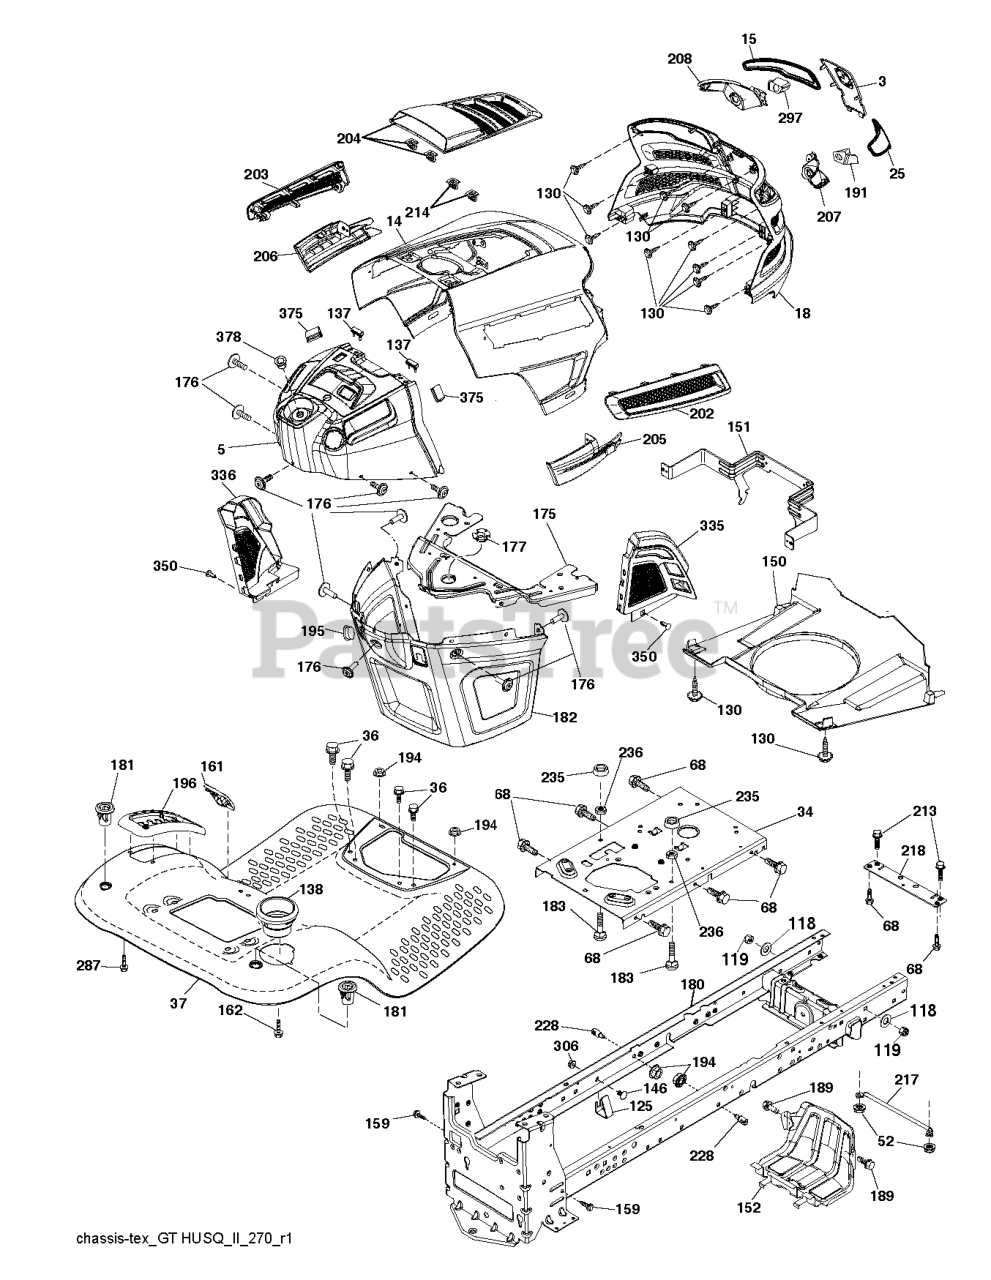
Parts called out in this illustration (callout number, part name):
3	APPLIQUE.SUBASM.GT.HUSQ.II
5	DASH.UPPER.ASM.GT2.SRV.MND.MAN
5	DASHBOARD.UPPER.ASM.GT2.X498
14	HOOD.ASM.HUSQVARNA.GT.TEX.ORAN
15	LENS.HEADLIGHT.LH.GTII.2011
18	Grilles
18	GRILLE SUBASM.GT.II.LOW.HDLGHT
25	LENS.HEADLIGHT.RH.GTII.2011
34	PLATE.ENGINE.WELDED.CHASSIS
36	SCREW 5/16"
37	FENDER.TLT.PDL.CNTRL.W/CPH.ORG
37	FENDER.TLT.FS.W/CPH/FW/RSF.668
118	WASHER
119	Nuts
125	CLIP.FUEL.LINE
137	BUMPER DASH
138	HOLDER.CUP.LT.GREY
146	BOLT.RDHD.SHT.SQNK.3/8-16X5/8
150	AIR.DUCT.GTV2(2.54"RING HEIGHT
150	AIR DUCT.GTV2(1.66"RING HEIGHT
151	BRACKET.PIVOT.HOOD.GT.HUSQ.II
152	SHIELD.BROWNING.PNT.GT.V2
159	SCREW, 3/8-16X3/4
161	WINDOW.FUEL.LT.HUSQ.TEX.498
175	PLATE.PNT.CROSSMEMBER.HUSQ/PRE
176	SCREW.#10-24X5/8.RN.QU
177	BUSHING STEERING
180	CHASSIS
181	BUSHING.MNT.FEND.CRGO.TEX.49
182	DASH.LOWER.COMMON.12V.ADAPTOR
182	DASH LOWER.HUSQ.PRED NO CRUISE
189	SCREW
191	INSERT.REFLECTIVE.RH.HUSQ.GTII
195	PLUG.HOLE.DASH.LOWER.12V.BLK
196	DECKLFT.CONSOL FULL ASSM GREY
202	VENT.SIDE.RH.GT.HUSQ.II.
203	VENT.SIDE.LH.GT.HUSQ.II.498
204	VENT.TOP.ASM.HUSQ.GT2
205	SIDE.TRIM.RH.GT.HUSQ.II
206	SIDE.TRIM.LH.GT.HUSQ.II.GRAY
207	HEADLIGHT.CUP.BEZEL.HUS.GT2.RH
208	HEADLIGHT.CUP.BEZEL.HUS.GT2.LH
213	SCREW HEXAGON HEAD SCREW 5/16-
214	CLIP.RETAINER.TINNER.
217	ROD.PIVOT.HOOD
218	X-PIECE.HOOD.STOP.NON/
228	STUD.W/"D"ANTI-ROTATION
228	STUD.FASTNER.W/ANTI-ROTATE
236	NUT.CENTERLOCK.5/16-
287	SCREW 1/4X20
297	INSERT.REFLECTIVE.LH.HUSQ.GTII
306	NUT LOCK FLG 3/8-16 UNC
335	COVER.LOWER.DASH.RH.BLACK
336	COVER-LH.LOWER.DASH.GT2.BLACK
350	CLIP.X-MAS.TREE
375	BUMPER CLIP-ON. DASH 1"
378	BUSHING FLANGE; PLASTIC
